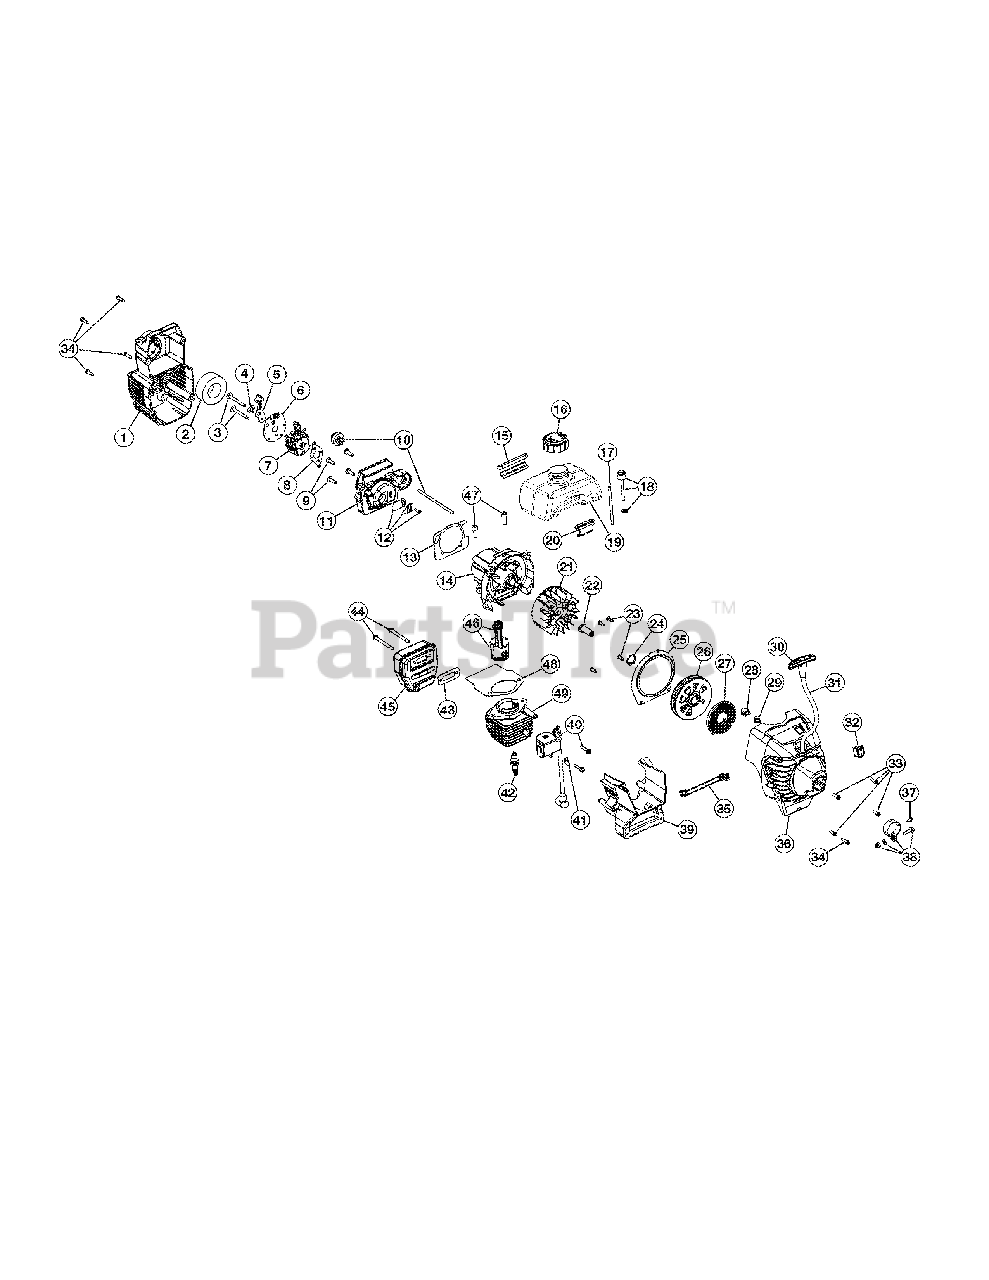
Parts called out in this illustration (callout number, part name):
1	Air Cleaner Cover Assembly (includes 2 & 34)
2	Air Cleaner Filter
3	Carburetor Mounting Screws
4	Wavey Washer
5	Choke Lever Assembly
6	Choke Lever & Plate (includes 5)
7	Carburetor Assembly (includes 8 & 19)
8	Carburetor Gasket
9	Carb Mount Screw
10	Primer and Hose Assembly
11	Carburetor Mount Assembly (includes 9, 12 & 13)
12	Reed Assembly
13	Carburetor Mount Gasket
14	Crankcase Service Assembly (includes 9)
15	Rear Mounting Pad
16	Fuel Cap Assembly
17	Fuel Return Line
18	Fuel Line Assembly
19	Fuel Tank Assembly (includes 16-18)
20	Front Mounting Pad
21	Flywheel Assembly
22	Square Nut Drive
23	Plate Screw
24	Palnut
25	Pressure Plate (includes 23 & 28)
26	Recoil Pulley Assembly (includes 24)
27	Recoil Spring
28	Eyelet Retainer
29	Rope Guide
30	Pull Handle
32	Switch Assembly
33	Housing Screw
34	Cover Screw
35	Wire Lead
36	Starter Housing Assembly (includes 23-35)
37	Anti-Rotation Screw
38	Clamp Assembly (includes 37)
39	Shroud Extension and Stand (includes 34)
40	Module Assembly
41	Ground Tab
42	Spark Plug
43	Exhaust Gasket
44	Muffler Mounting Bolt Assembly
45	Muffler Assembly (includes 43, 44 and Spark Arrestor)
46	Piston & Rod Assembly
47	Cylinder Bolt
48	Cylinder Gasket
49	Cylinder Assembly (includes 47 & 48)
